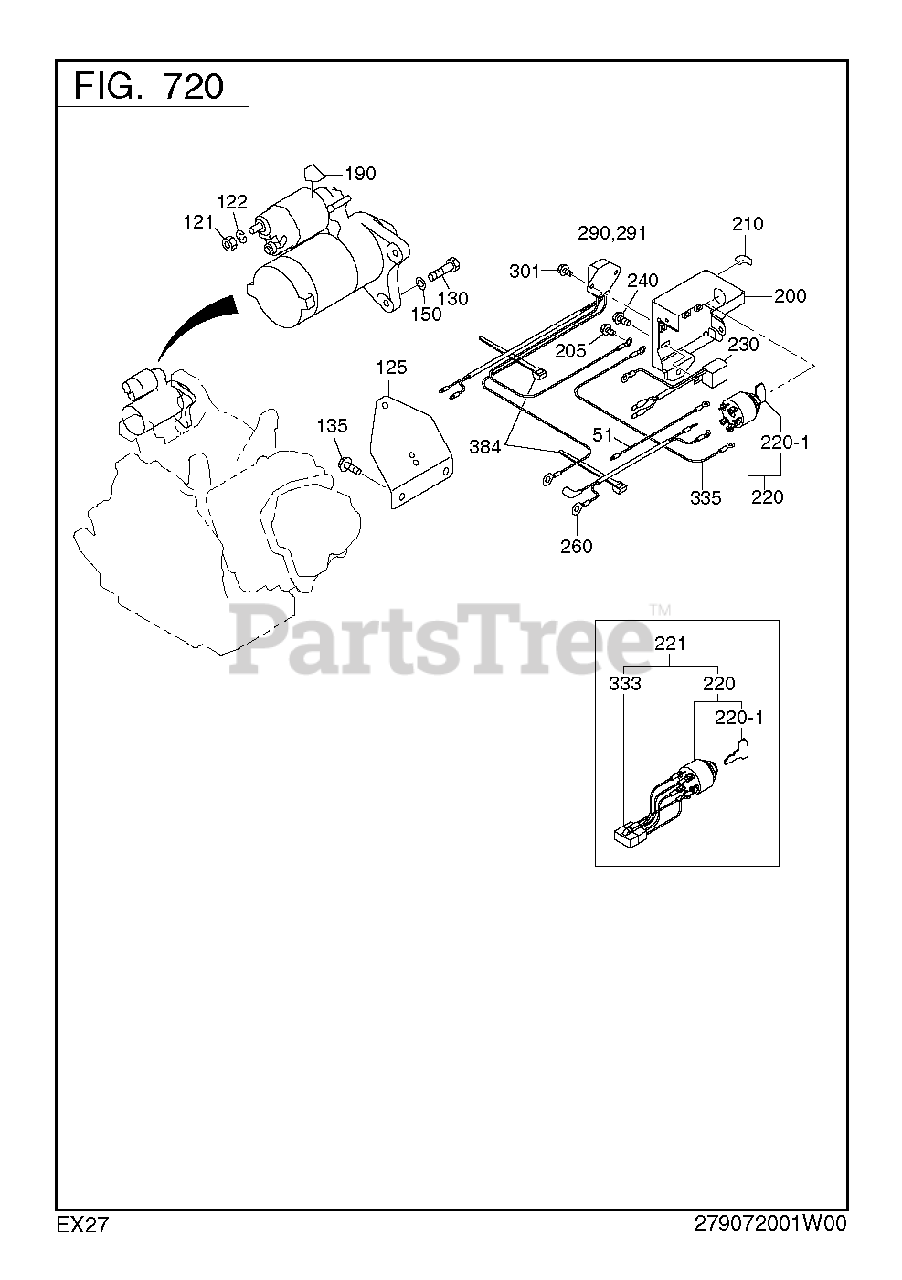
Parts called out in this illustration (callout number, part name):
51	WIRE 5 CP
125	BRACKET(SEL) CP
130	BOLT CP,STARTER
135	FLANGE BOLT
150	WASHER
190	LABEL(BATTERY)
200	CONTROL BOX CP
205	BOLT AND WASHER AY
210	LABEL(STARTER SWITCH
220	SWITCH
230	DIODE RECTIFIER CP
240	SCREW AND WASHER AY
260	WIRE 3 CP
335	WIRE 4 CP
384	WIRE BAND
